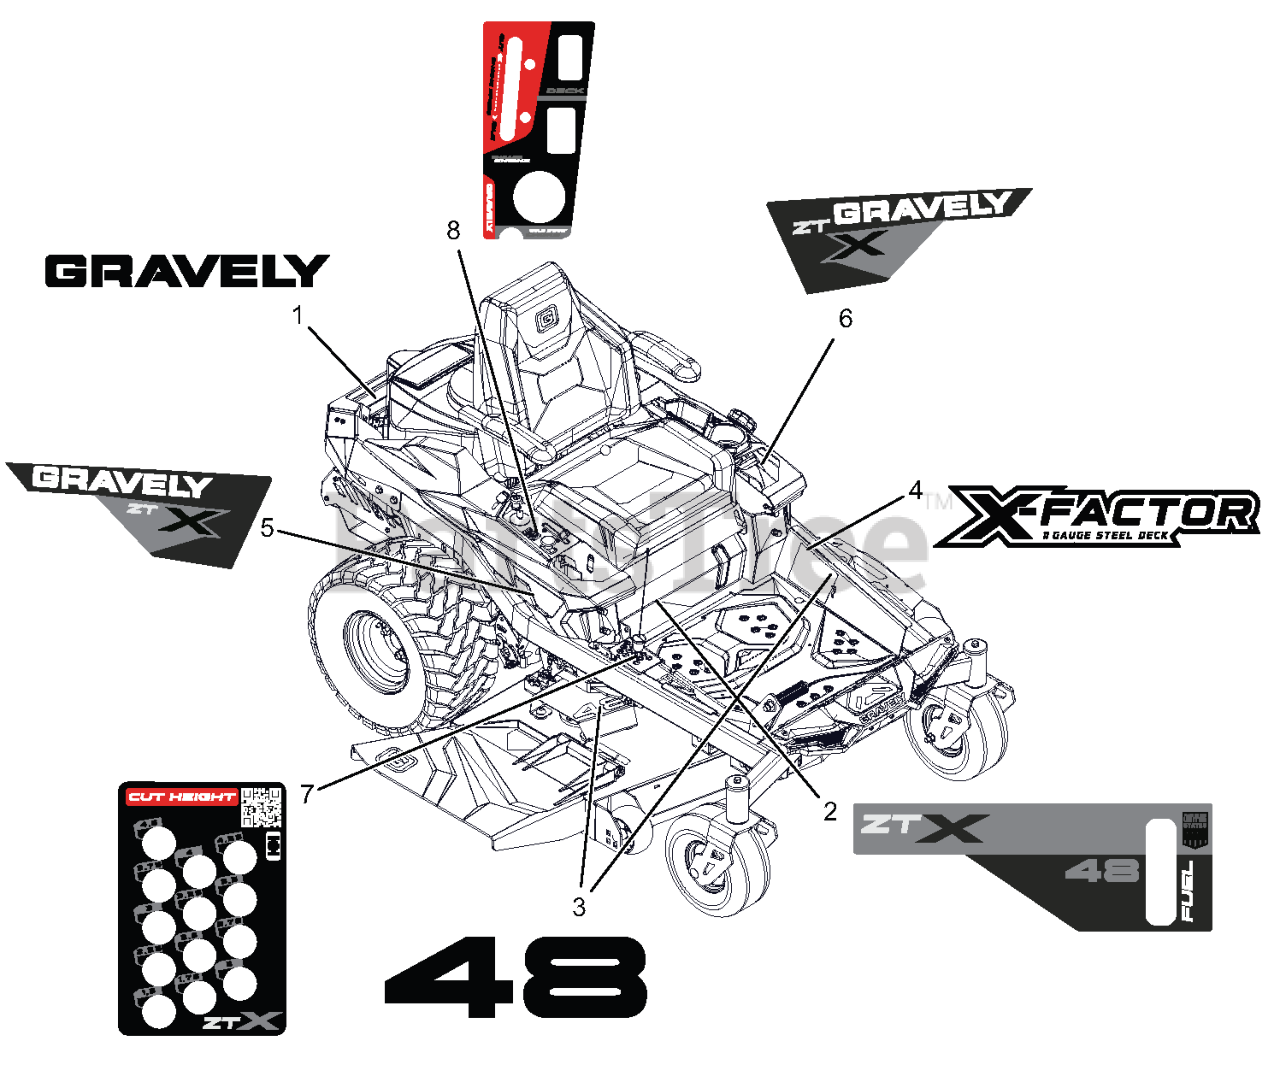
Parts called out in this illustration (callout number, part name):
1	DECAL- GRAVELY
2	DECAL- ZTXL 48-KICK PLATE
3	DECAL- DECK 48"
4	DECAL- DECK X-FACTOR
5	DECAL- ZT X FENDER RH
6	DECAL- ZT X FENDER LH
7	DECAL- HEIGHT OF CUT-X
8	DECAL- CONTROL PANEL-GRAVELY
